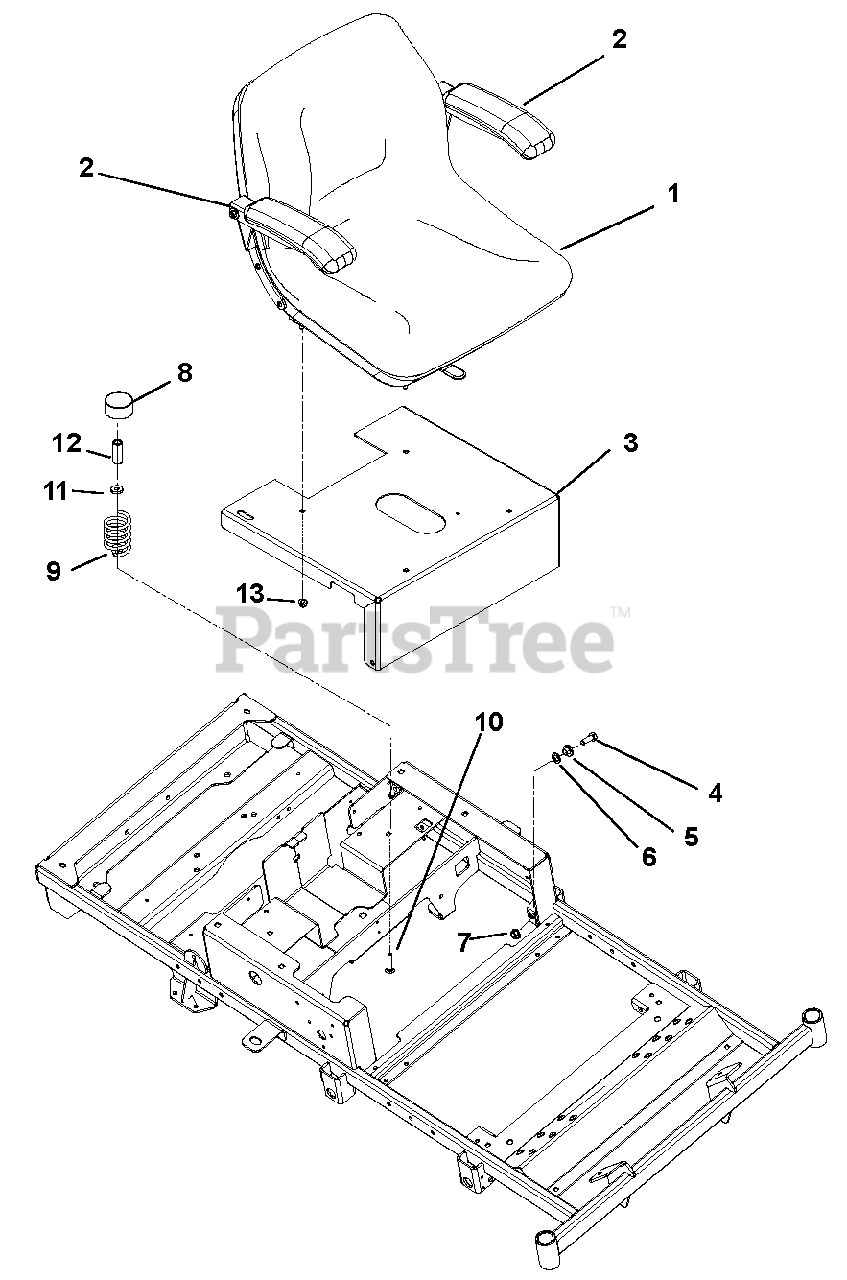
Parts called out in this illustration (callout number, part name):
1	Seat with Arm
2	Arm Rest Kit
3	Seat Plate
4	Bolt, Hex .38-16 x 1.00 Grade 5
5	Bushing, Flange .385 x .500 x .875 x .406
6	Washer, Flat Steel .52 x .827 x .062
7	Nut, .38-16 Nyloc Flange
9	Spring, Seat
10	Bolt, Round Head Square Neck .31-18 x 1.50 Grade 5
11	Washer, Flat Steel .328 x .87 x .179
12	Nut, Coupling 5/16-18 x 1 .75
13	Nut, 5/16-18 Flange Nyloc
